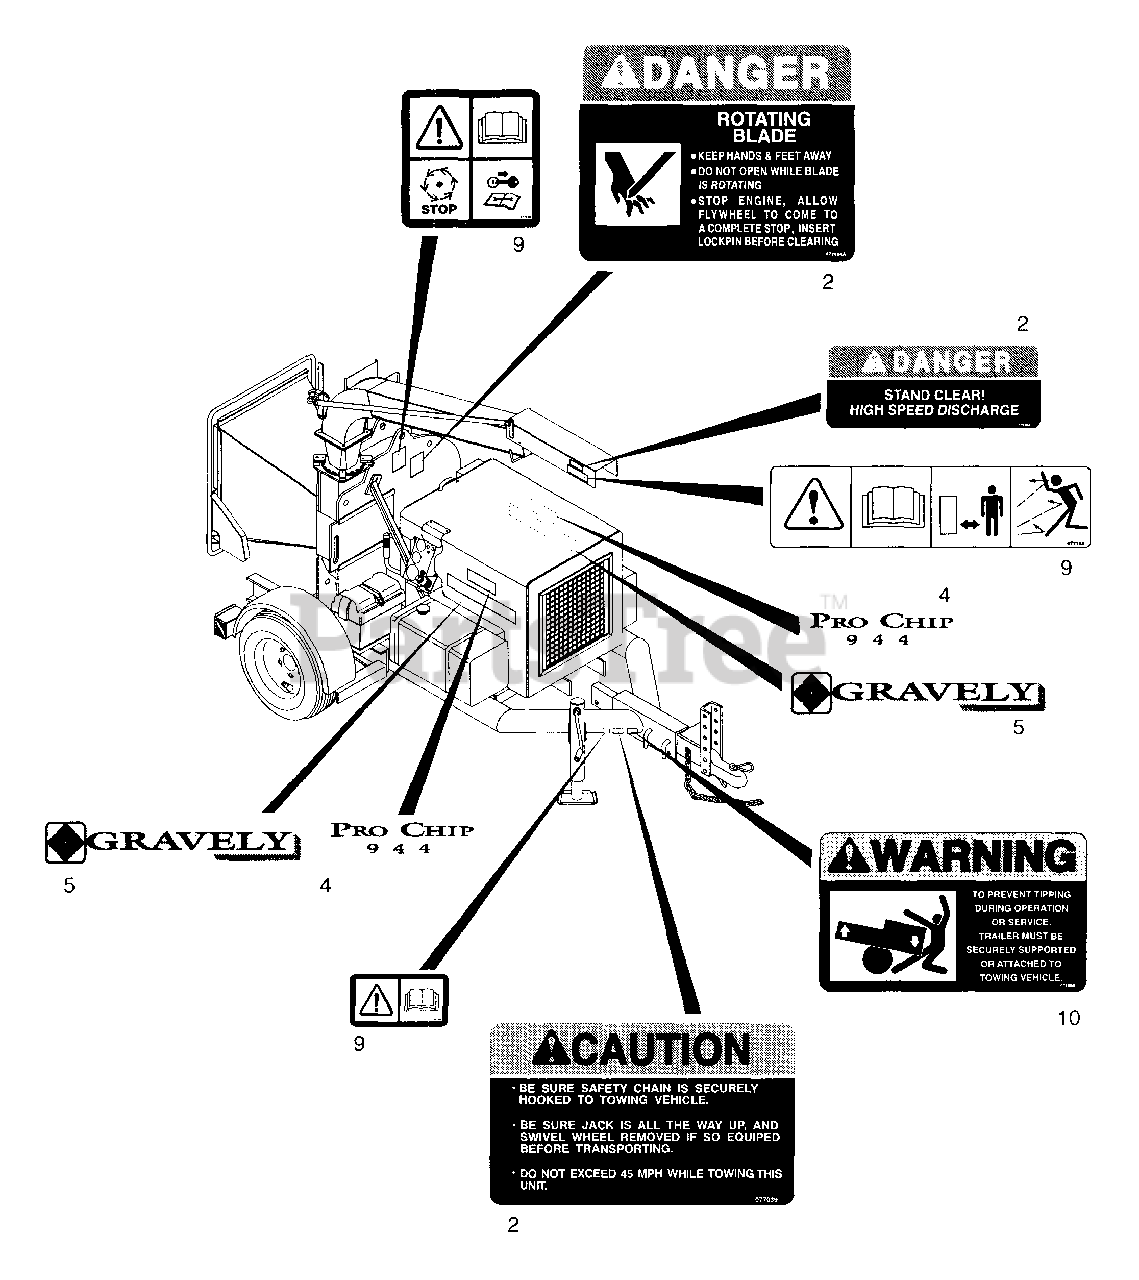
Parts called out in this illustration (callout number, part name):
2	Decal-Set Large Chippers
4	Decal-Model Designation 944
5	Decal-Warning-Protective
9	Decal-Set Chipper CE
10	Decal-Warning-Tipping
